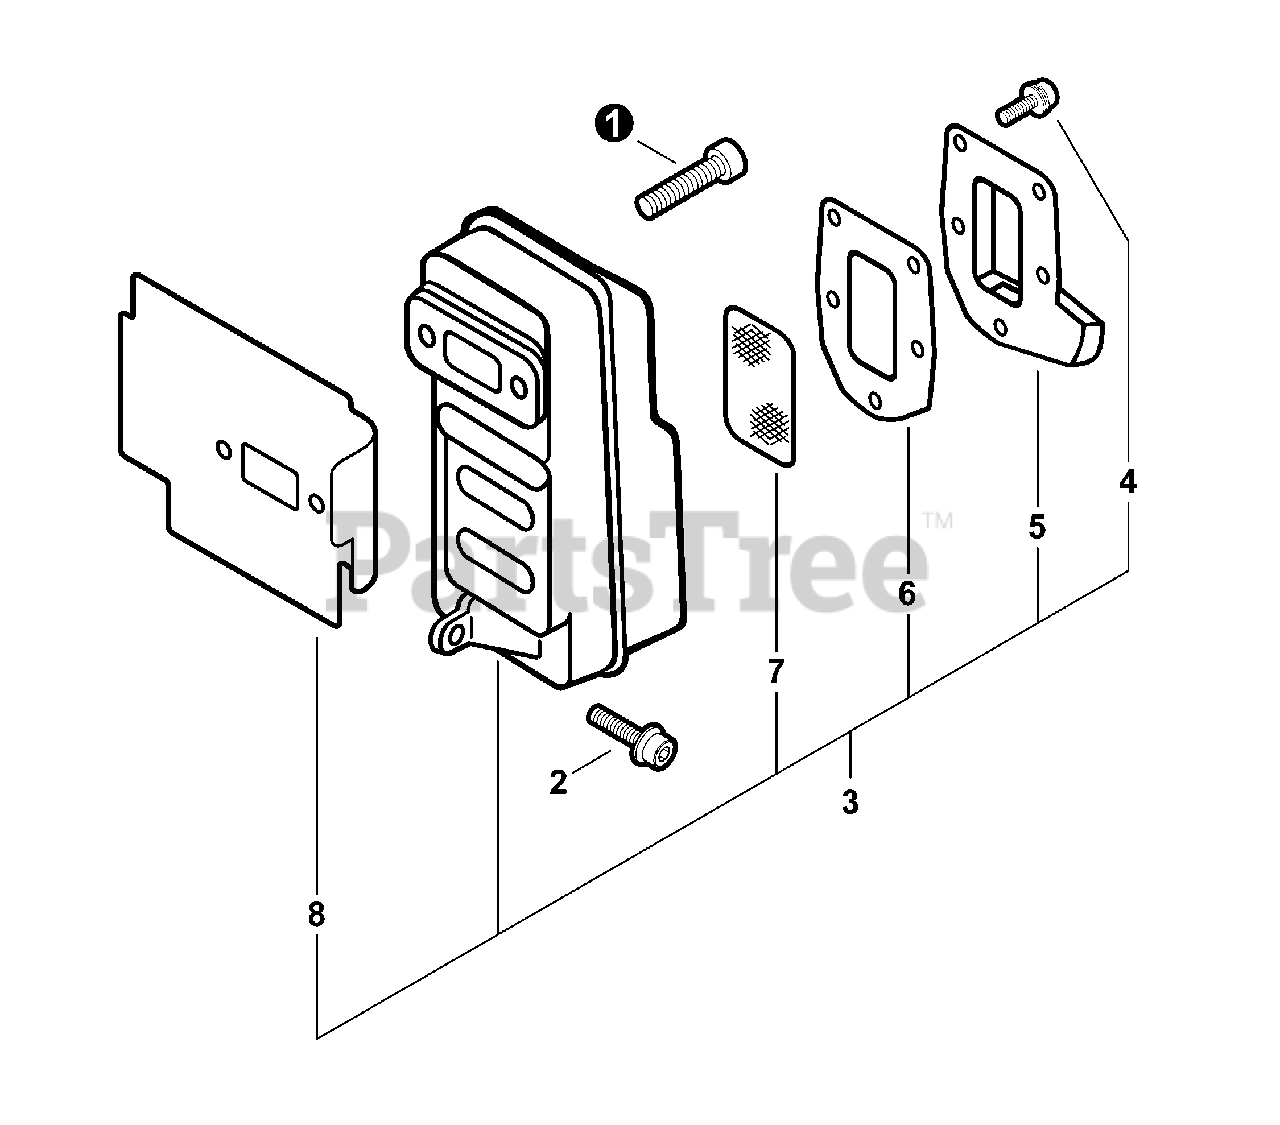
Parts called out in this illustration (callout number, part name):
1	SCREW - 6×20
2	SCREW - 5×16
3	MUFFLER ASSY
4	SCREW - 4×10
5	GUIDE, EXHAUST
6	GASKET, EXHAUST
7	SCREEN, SPARK ARRESTOR
8	SHIELD, EXHAUST
